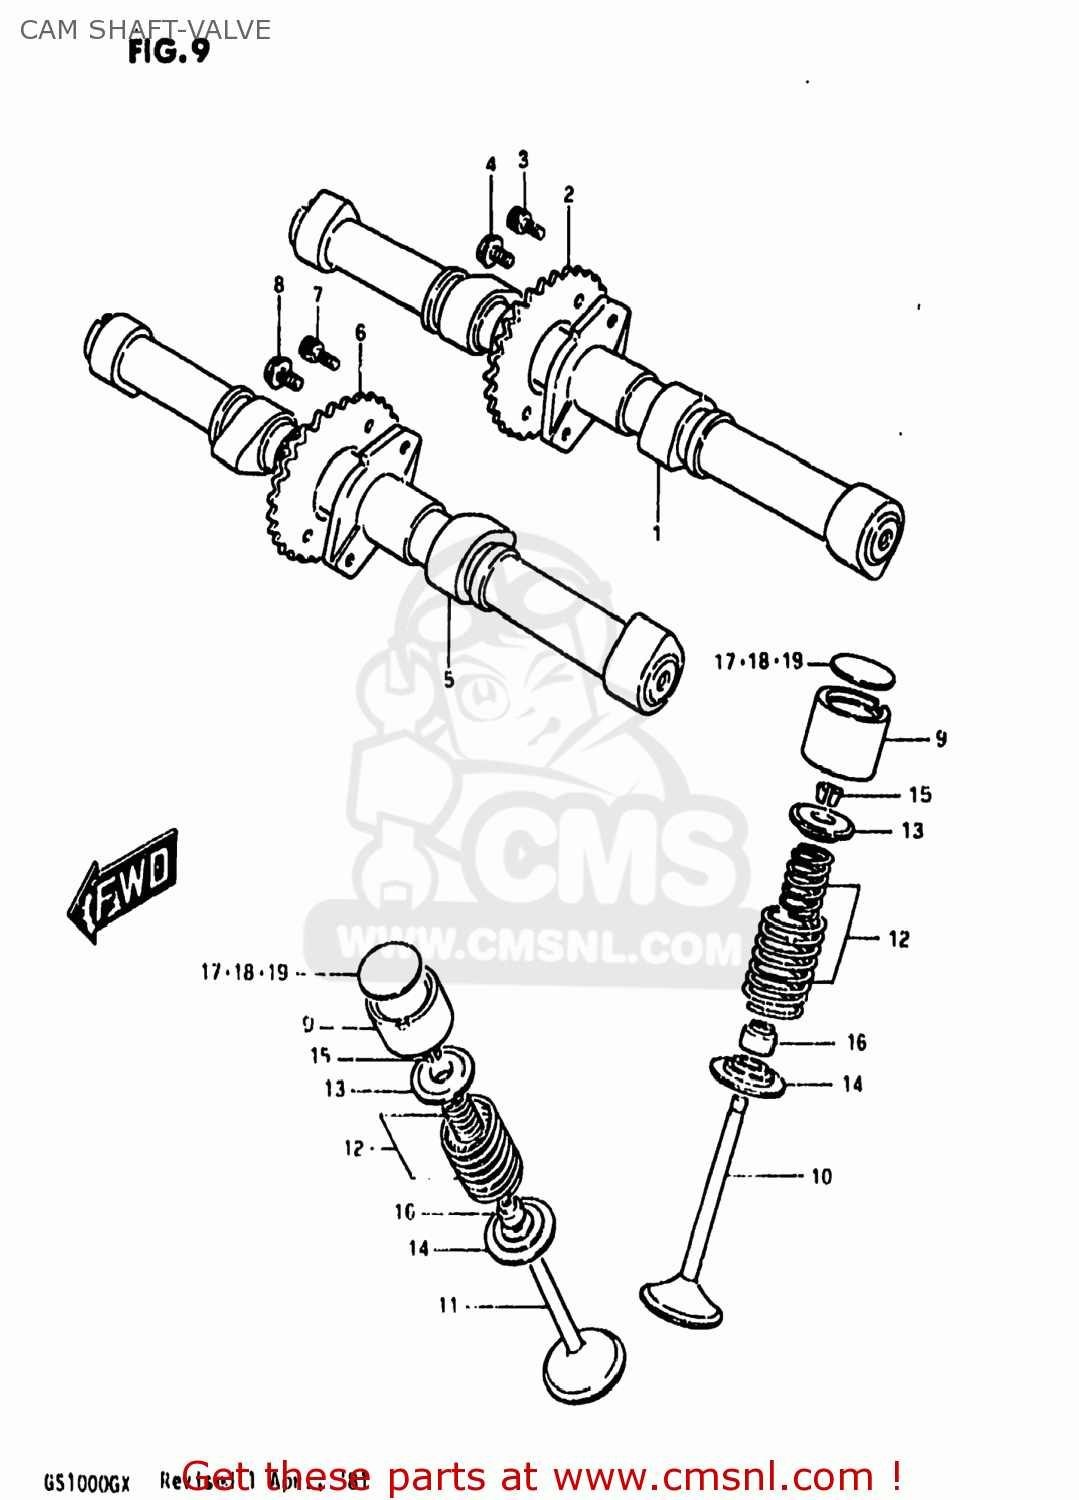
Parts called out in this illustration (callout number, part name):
1	CAMSHAFT
2	SPROCKET,INTAKE CAMSHAFT
3	BOLT 6X11
4	BOLT(7X11)
5	CAMSHAFT,EXHAUST
6	SPROCKET,EXHAUST CAMSHAFT
7	BOLT 6X11
8	BOLT(7X11)
9	TAPPET
10	VALVE,INTAKE
11	VALVE,EXHAUST
12	SPRING SET,VALVE
13	RETAINER,VALVE SPRING
14	SEAT,VALVE SPRING
15	COTTER VALVE
16	SEAL,OIL(7X14.4X9)
17	SHIM,TAPPET
18	SHIM,TAPPET
19	SHIM,TAPPET
20	SHIM SET,TAPPET
21	CASE
